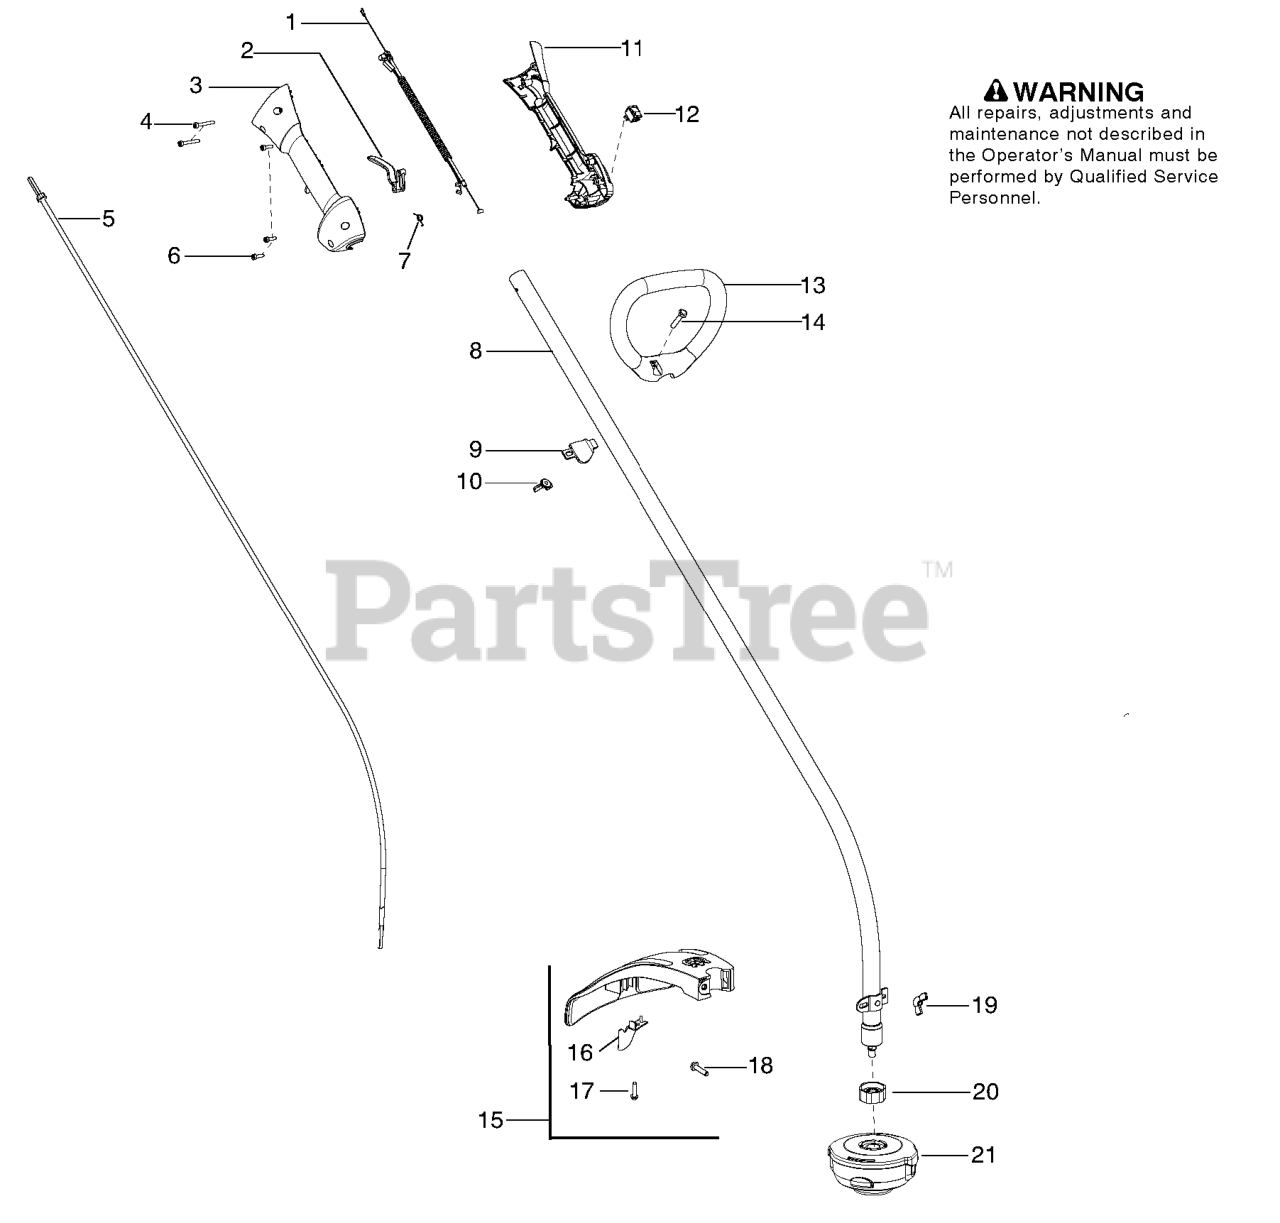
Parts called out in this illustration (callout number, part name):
1	Assy-Cable/Wire Harness
2	TRIGGER THROTTLE
3	HOUSING-THROTTLE (RH)
5	Flexshaft
6	SCREW M4 X 1.75 PT 16MM
7	SPRING TRIGGER
8	DRIVESHAFT KIT
9	CLAMP ASSIST HANDLE
10	WINGNUT, TYPE 2
11	HSG THROTTLE LH
12	KIT SWITCH
13	HANDLE ASSIST
14	BOLT, TYPE 2
15	TRIMMER GUARD 128C
16	KIT - LIMITER - LINE
18	BOLT, TYPE 2
19	WINGNUT, TYPE 2
21	Assy-T25 Cutting Head
